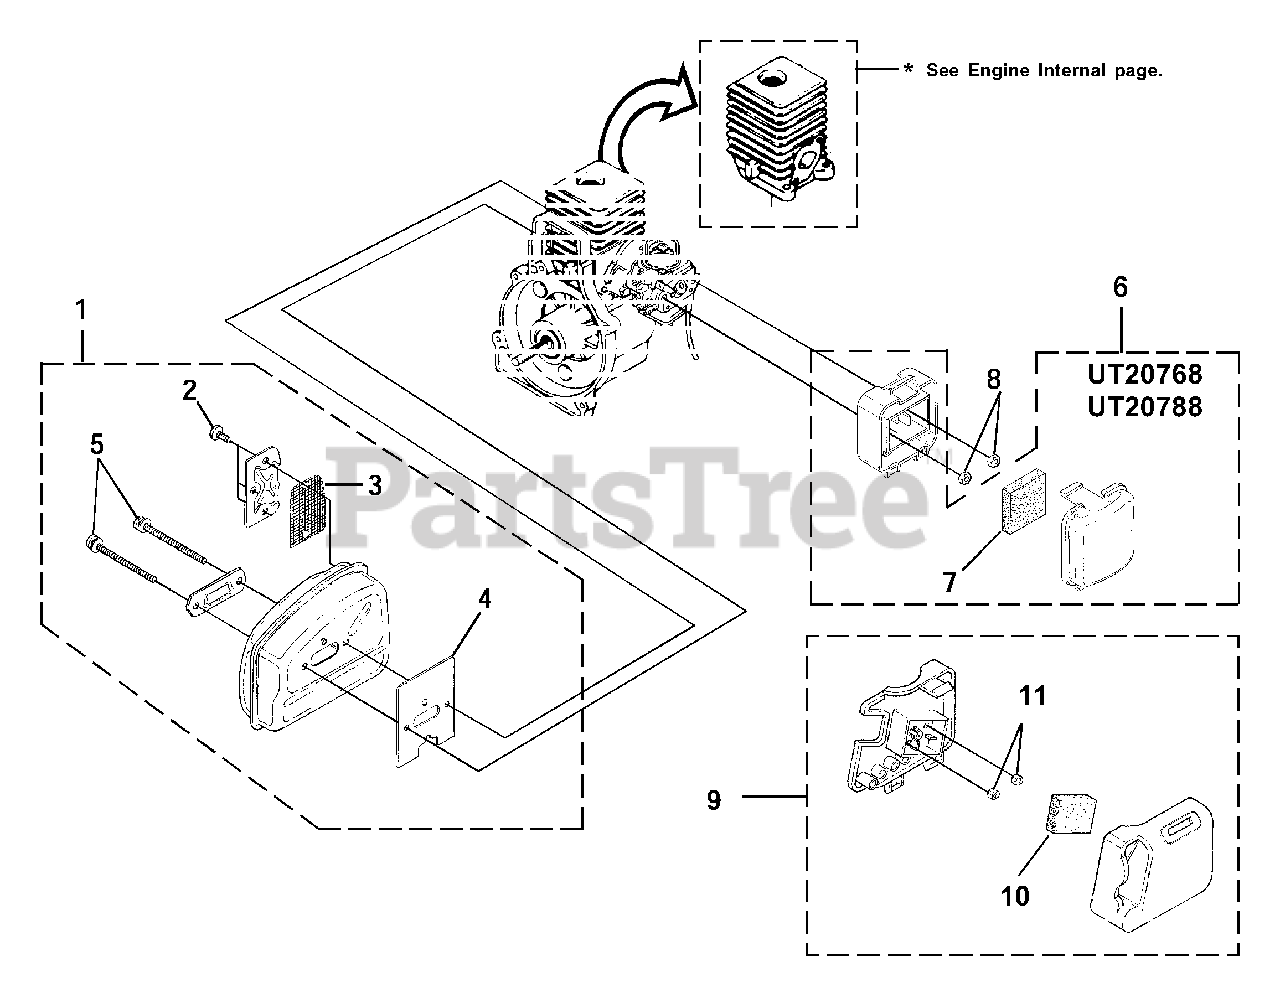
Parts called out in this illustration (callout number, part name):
1	MUFFLER ASSEMBLY
2	SCREW, Taptite - (8-32 X 3/8")
3	SCREEN-Spark
4	GASKET-Muffler
5	SCREW, Truss Hd. - (10-24 X 2.188)
6	AIR FILTER KIT (UT20768, UT20788)
7	FILTER-AIR
8	NUT-Hex (10-24)
9	AIR FILTER KIT
10	FILTER-Air
11	NUT-Hex (10-24)
